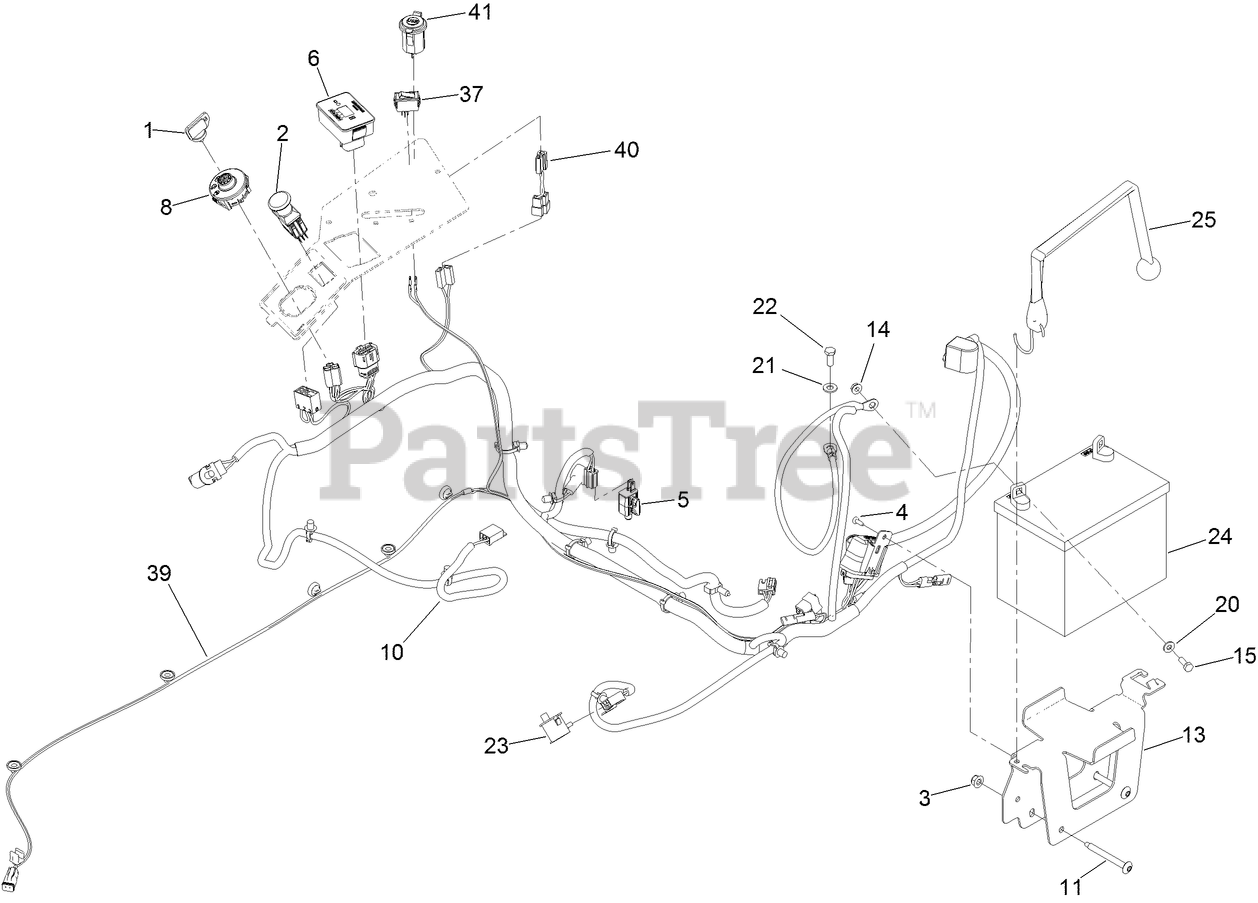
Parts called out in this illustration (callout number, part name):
1	KEY-IGNITION
2	SWITCH-PTO
3	NUT-HF, NI
4	SCREW-FORMING, THREAD
5	SWITCH
6	MODULE ASM
8	SWITCH-IGNITION
10	HARNESS-WIRE
11	SCREW-TORX
13	TRAY-BATTERY
14	NUT-HF
15	SCREW-HH
20	WASHER-FLAT
21	WASHER-PLAIN
22	SCREW-HH
23	SWITCH-BAIL
24	BATTERY
25	STRAP-BUNGEE
37	SWITCH-ROCKER
39	HARNESS - WIRE
40	HARNESS-WIRE, USB KIT
41	PORT-POWER, USB
